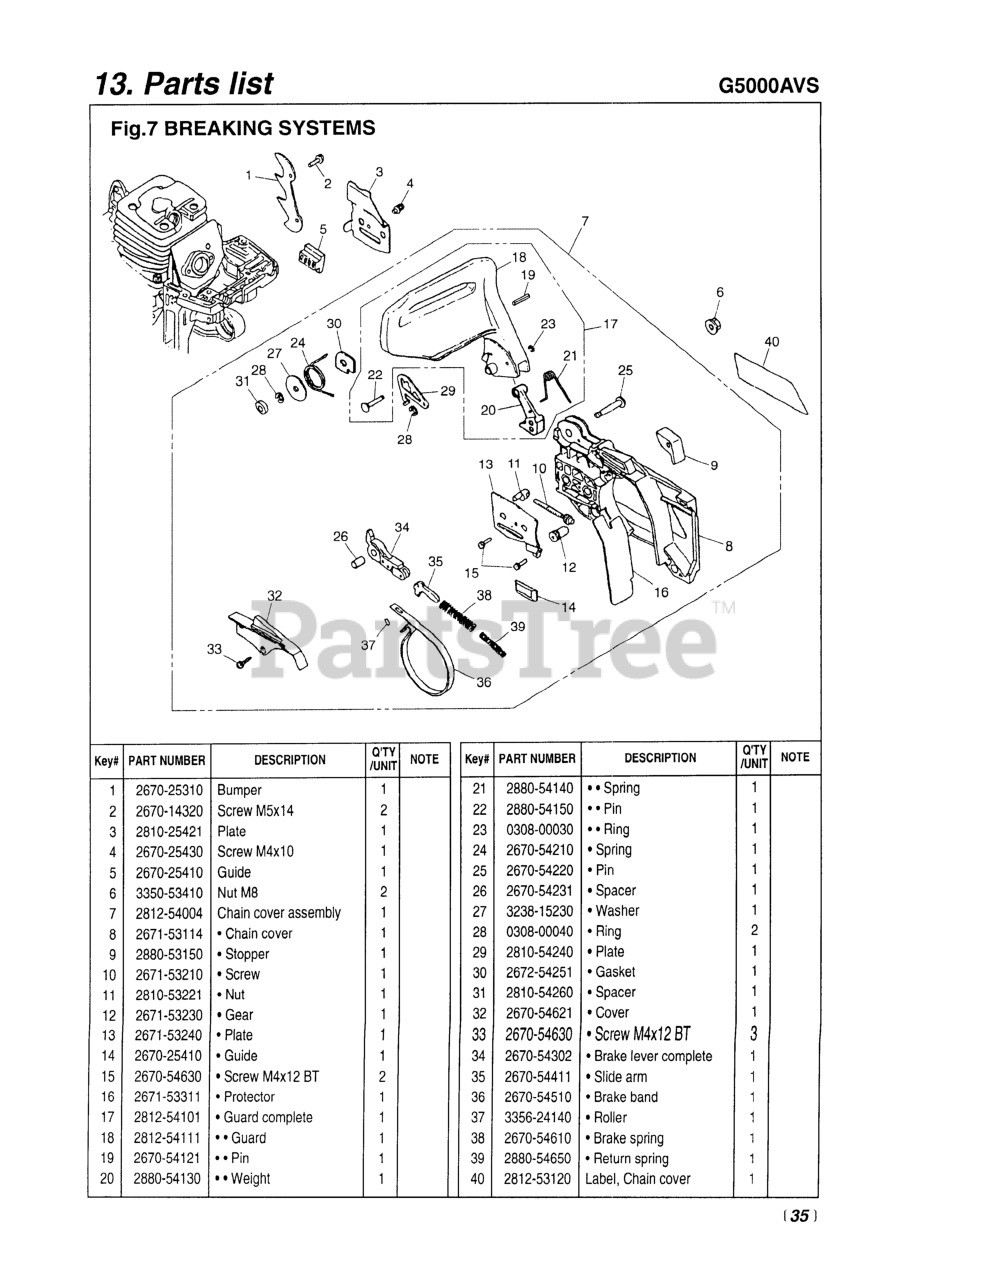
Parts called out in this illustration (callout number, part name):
1	SPIKE
2	SCREW (REPLACES 2616-24320)
3	PLATE (REPLACES 2670-25422)
5	GUIDE, CHAIN
6	NUT
7	CHAIN COVER ASSY (RPLS -54003)
9	STOPPER
10	SCREW
11	NUT
12	GEAR
14	GUIDE, CHAIN
15	SCREW
16	PROTECTOR
17	GUARD COMPLETE
18	GUARD (RPLS 2672-54110)
19	PIN, STOPPER
20	WEIGHT, ACTION
21	848-C8E-54D1
22	PIN, SPRING
23	RING, SNAP, M3
24	SPRING, RETURN
25	PIN
27	WASHER
28	RING, SNAP, M4
29	PLATE (RPLS 2670-54241)
30	GASKET (RPLS 2672-54250)
32	COVER (REPLACES -54620)
33	SCREW
34	LEVER (REPLACES 2670-54301)
35	ARM, SLIDE(RPLS 2670-54410)
36	BAND, BRAKE
37	PIN
38	SPRING, BRAKE (RPLS. 50030121)
40	LABEL, CHAIN COVER
